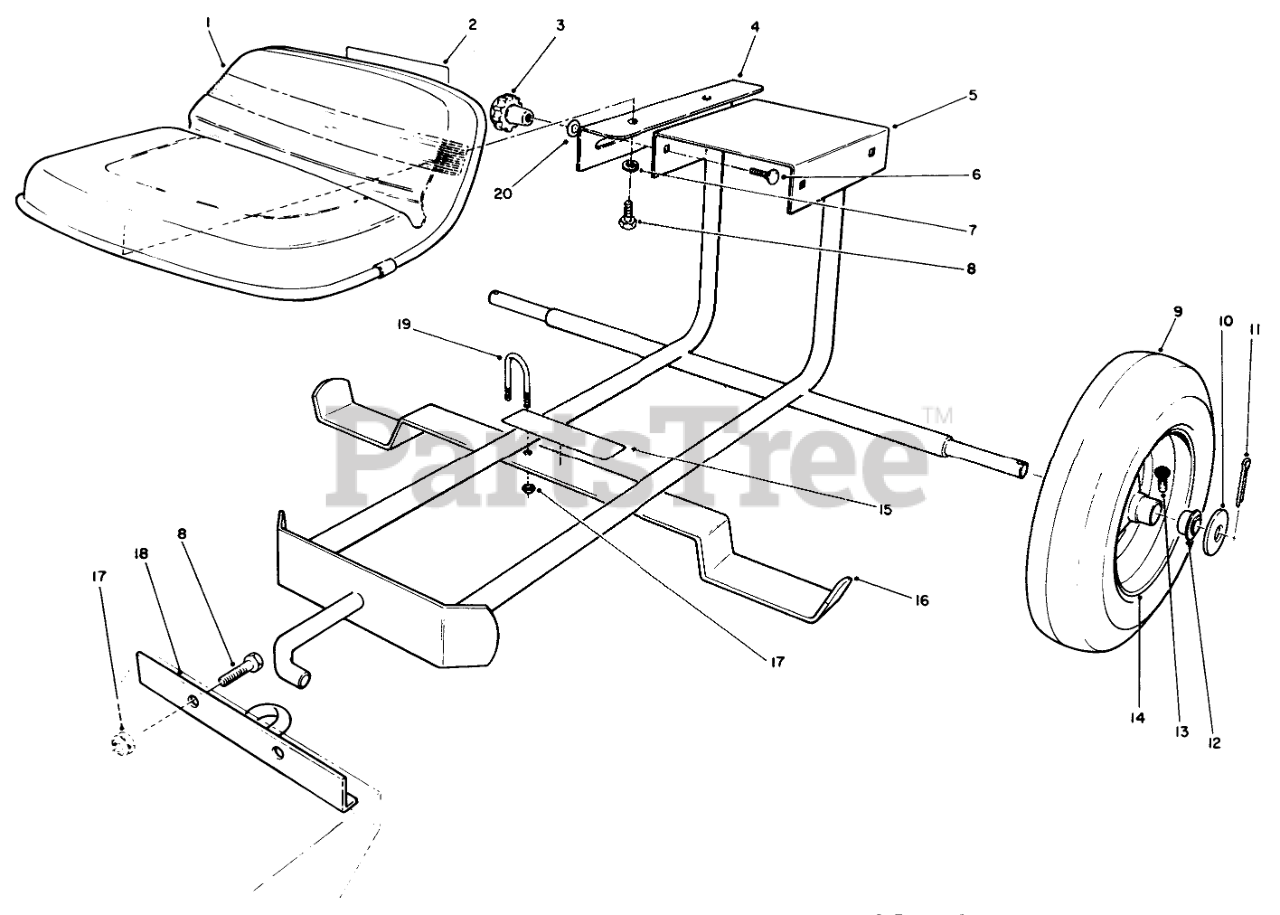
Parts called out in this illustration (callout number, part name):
1	Seat
2	DECAL
4	BRACKET R
5	Frame Assembly
6	BOLT-CARR
7	WASHER-LOCK
8	SCREW-HH
10	WASHER-FLAT
11	PIN-COTTER
12	BEARING
13	VALVE STEM-INNER TUBE
14	WHEEL
15	SULKY DECAL
16	SULKY FOOTREST R
17	NUT-LOCK, NI
18	HITCH
19	U-BOLT
20	WASHER-BELLEVILLE
